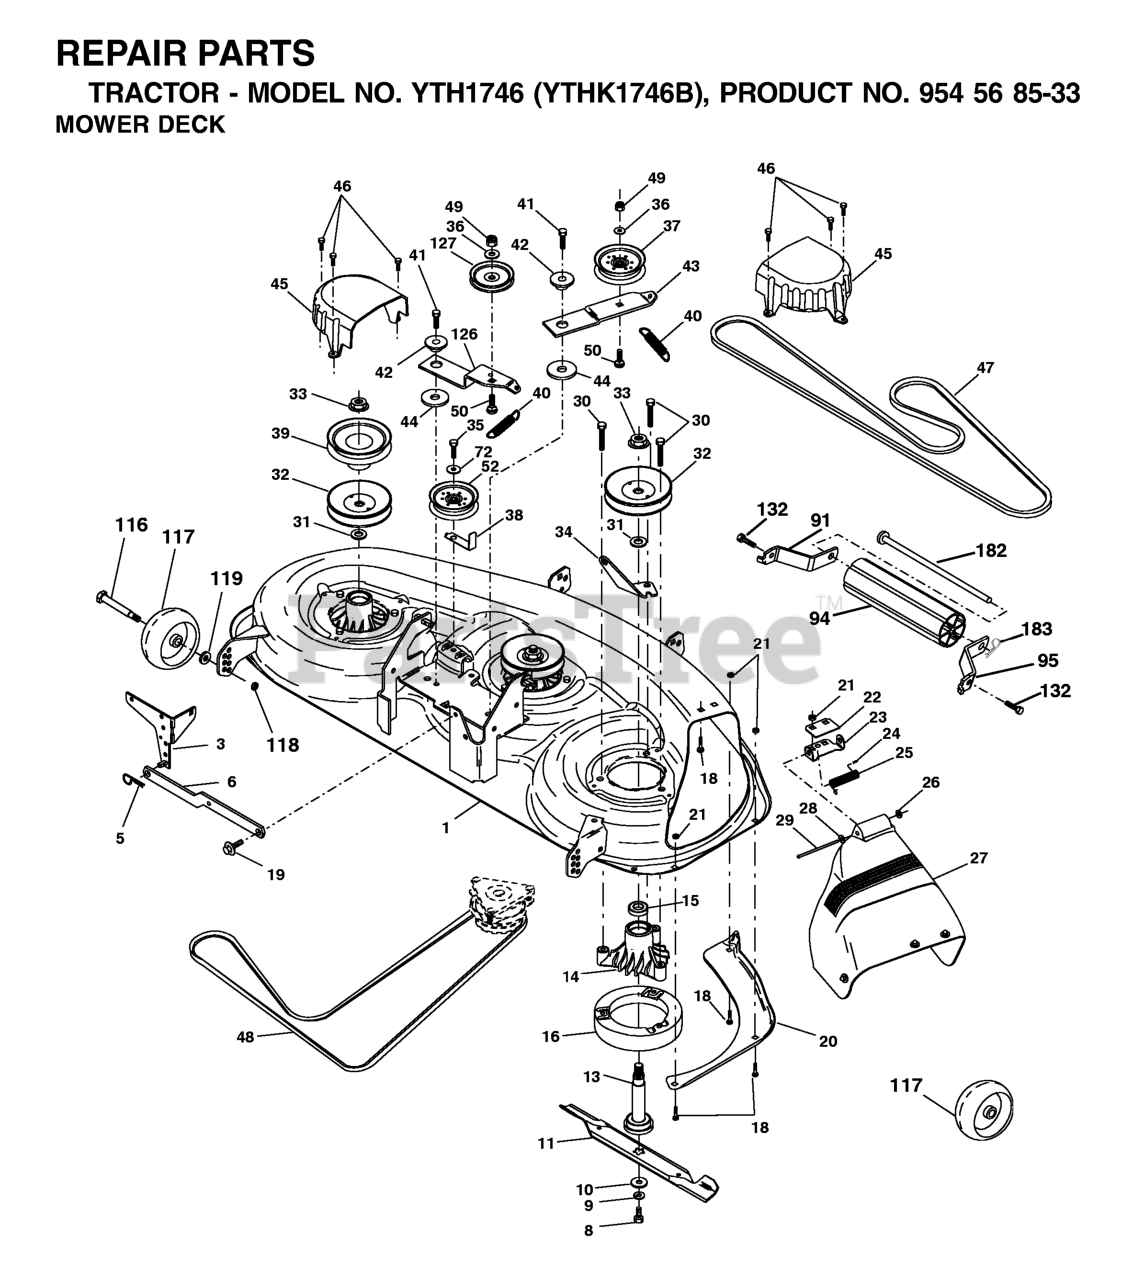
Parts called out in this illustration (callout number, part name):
2	MUFFLER.TWIN.CYL.LOW.TONE
9	KEEPER.BELT.ENGINE.3.25 (3 2)
11	RB.CLUTCH.OGURA.4.4.PD
12	PULLEY.ASM.ENG.OGURA.3
15	TANK.FUEL.4GAL
18	CAP.FUEL.TANK.3"GREY
20	THROTTLE CONTROL
21	SCREW
22	CONTROL, CHOKE
28	REPL BY 532 00 85-43
29	KIT.SPARK ARRESTOR 794945 B&S
37	HOSE CLAMP
42	LOCKWASHER
45	NUT
62	RP SHIELD HEAT MUFFLER
70	EXHAUST TUBE LH KAWI
71	EXHAUST TUBE RH KAWI
81	TUBE, DRAIN OIL ASM.
85	BOLT HEX 7/16-20X4-1/4"
86	NUT.HEX.FLANGE.TOPLOCK
87	BOLT.5/16-18UNCX1.W/SEMS.BLK
90	SCREW 3/8-16X1
92	SCREW 3/8-16X1
